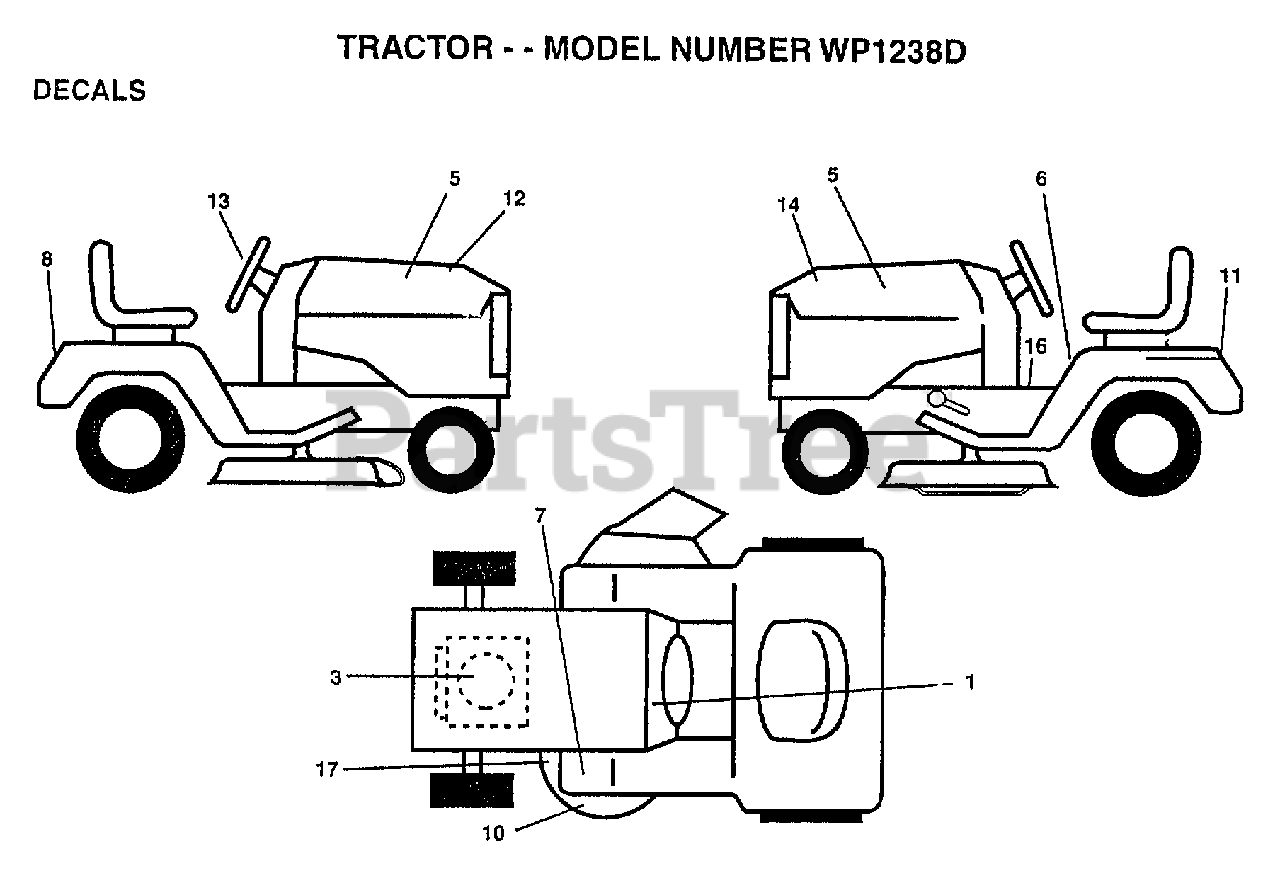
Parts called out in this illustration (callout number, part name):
1	"DECAL-OPER,GEAR D"
3	DECAL, HP ENGINE
5	DECAL.HOOD.LOGO.
6	"DECAL DANGER,FEND"
8	DECAL, FENDER LOGO
11	DECAL.BATRY.3-3908
12	DECAL.HD.RH.WINST
13	DECAL, WHEEL CAP
14	DECAL.HD.LH.WINST
16	DECAL BRAK PARK
17	DECAL
